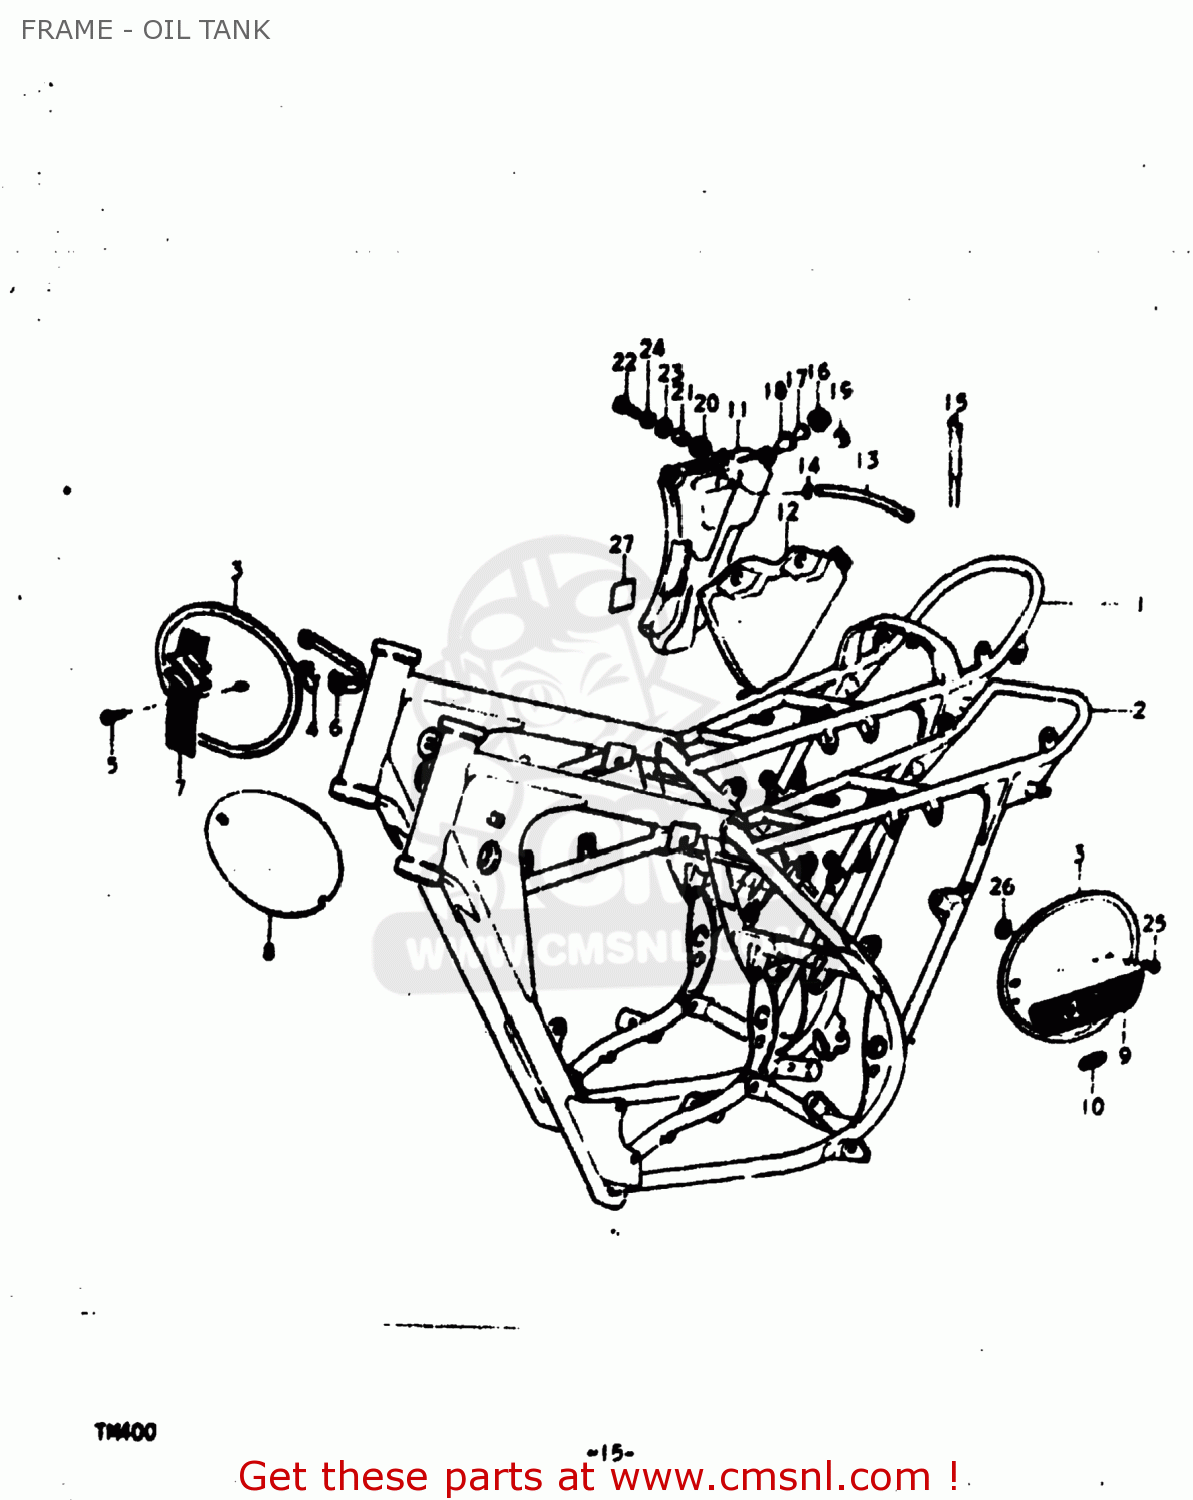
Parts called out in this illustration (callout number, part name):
1	FRAME
2	FRAME
3	PLATE,NUMBER,FRONT
5	SCREW
6	BAND
7	EMBLEM,FRONT NUMBER PLATE
8	EMBLEM,FRONT NUMBER PLATE
9	EMBLEM,FRONT NUMBER PLATE
10	EMBLEM,CCIS
11	TANK,OIL
12	TANK,OIL
13	HOSE
14	CLIP
15	CLAMP
16	CAP, OIL TANK
17	GASKET,OIL TANK CAP (NAS)
18	GASKET,OIL TANK CAP
19	GASKET,OIL TANK (NAS)
20	CUSHION
21	SPACER (6.8X10X10)
22	BOLT
23	WASHER (6.5X20X1.2)
24	LOCK WASHER
25	BOLT
26	WASHER
27	LABEL
